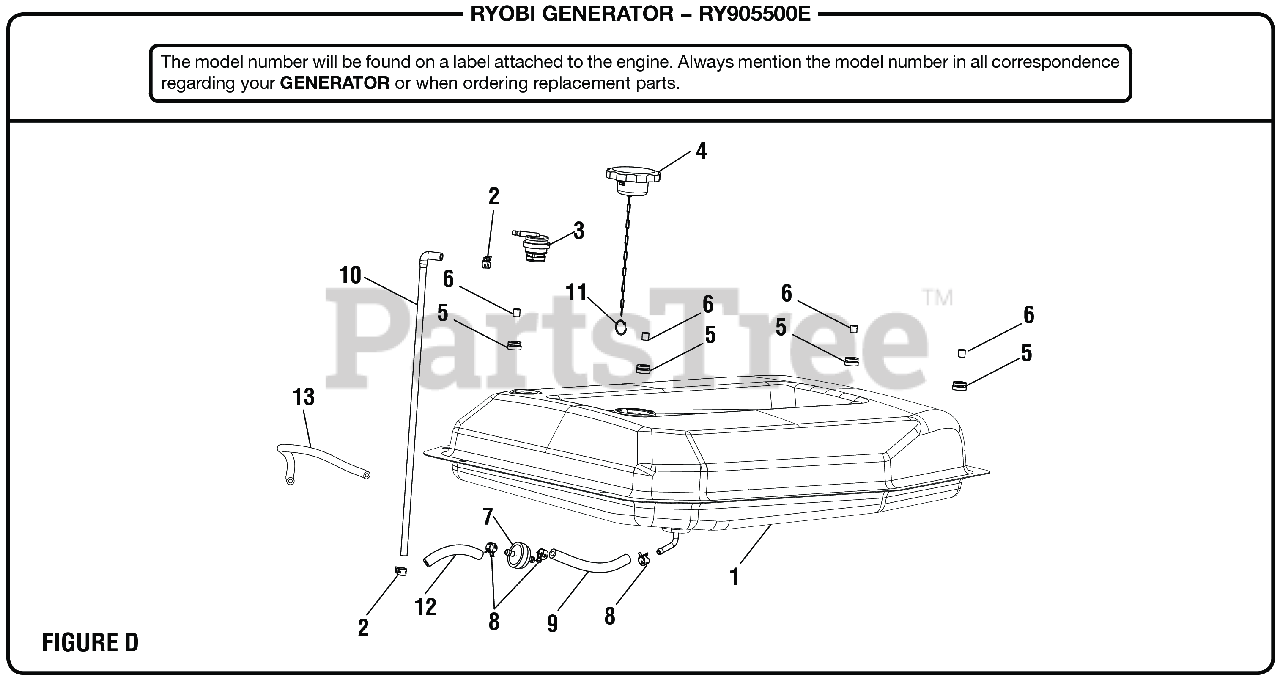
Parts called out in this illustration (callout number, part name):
1	Fuel Tank Assembly (See Fig. B)
2	Fuel Line Clamp (7/16 in., BM903611)
3	Fuel Tank Vapor Vent
4	Fuel Cap Assembly
5	Bushing (Fuel Tank Isolator)
6	Spacer (Fuel Tank Isolator)
7	Fuel Filter Inline (1/4 in.)
8	Fuel Line Clamp (1/2 in.).
9	Fuel Hose (175 mm)
10	Vapor Hose
11	Ring Clip
12	Fuel Hose (85 mm)
13	Fuel Hose (330 mm)
